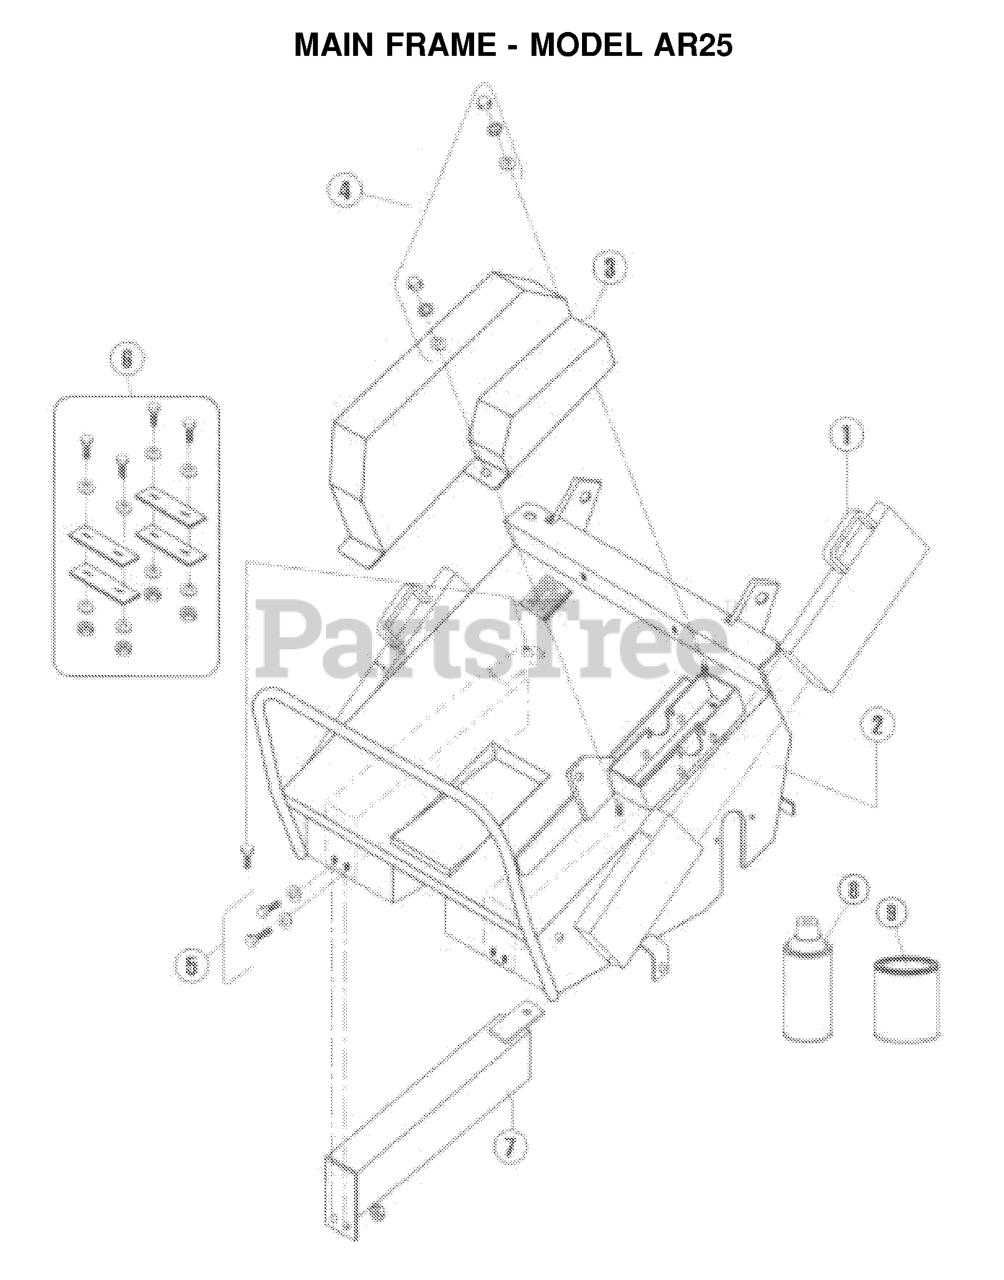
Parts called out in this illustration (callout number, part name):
1	WEIGHT, 36LBS
3	DRIVE GUARD
4	FASTENER KIT
5	FASTNER KIT
6	PLATE KIT FOR HONDA
7	36 IB WEIGHT, MOUNTED
